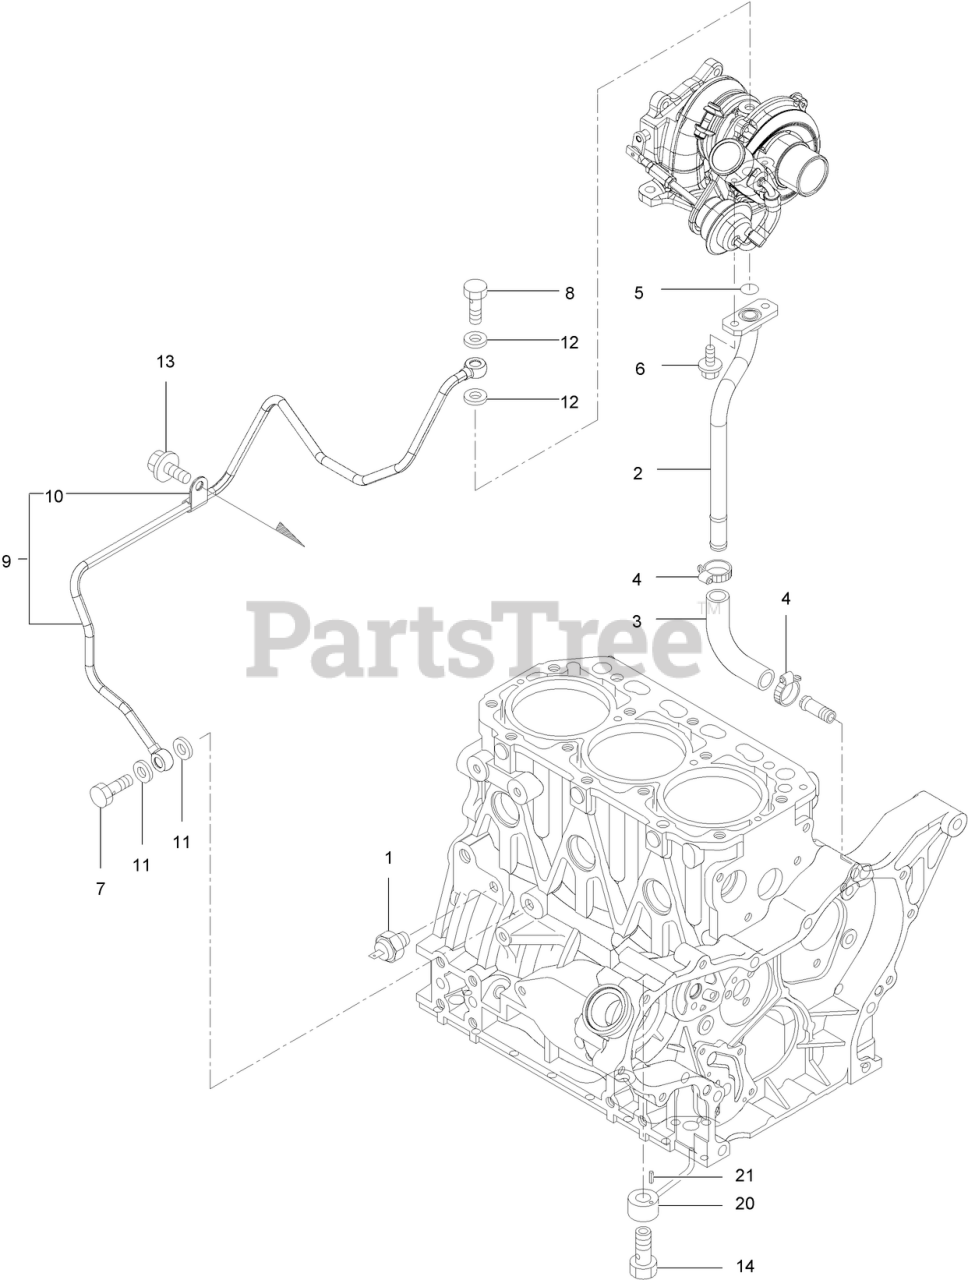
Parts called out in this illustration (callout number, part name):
1	SWITCH-OIL
2	PIPE, OIL RETURN
4	CLAMP-HOSE
5	O-RING
7	BOLT-JOINT, PIPE
8	BOLT-JOINT, PIPE
9	LUBE OIL PIPE ASM
10	RETAINER
11	WASHER-SEAL
12	GASKET
14	CHECK VALVE ASM
20	NOZZLE
21	PIN-SPRING
